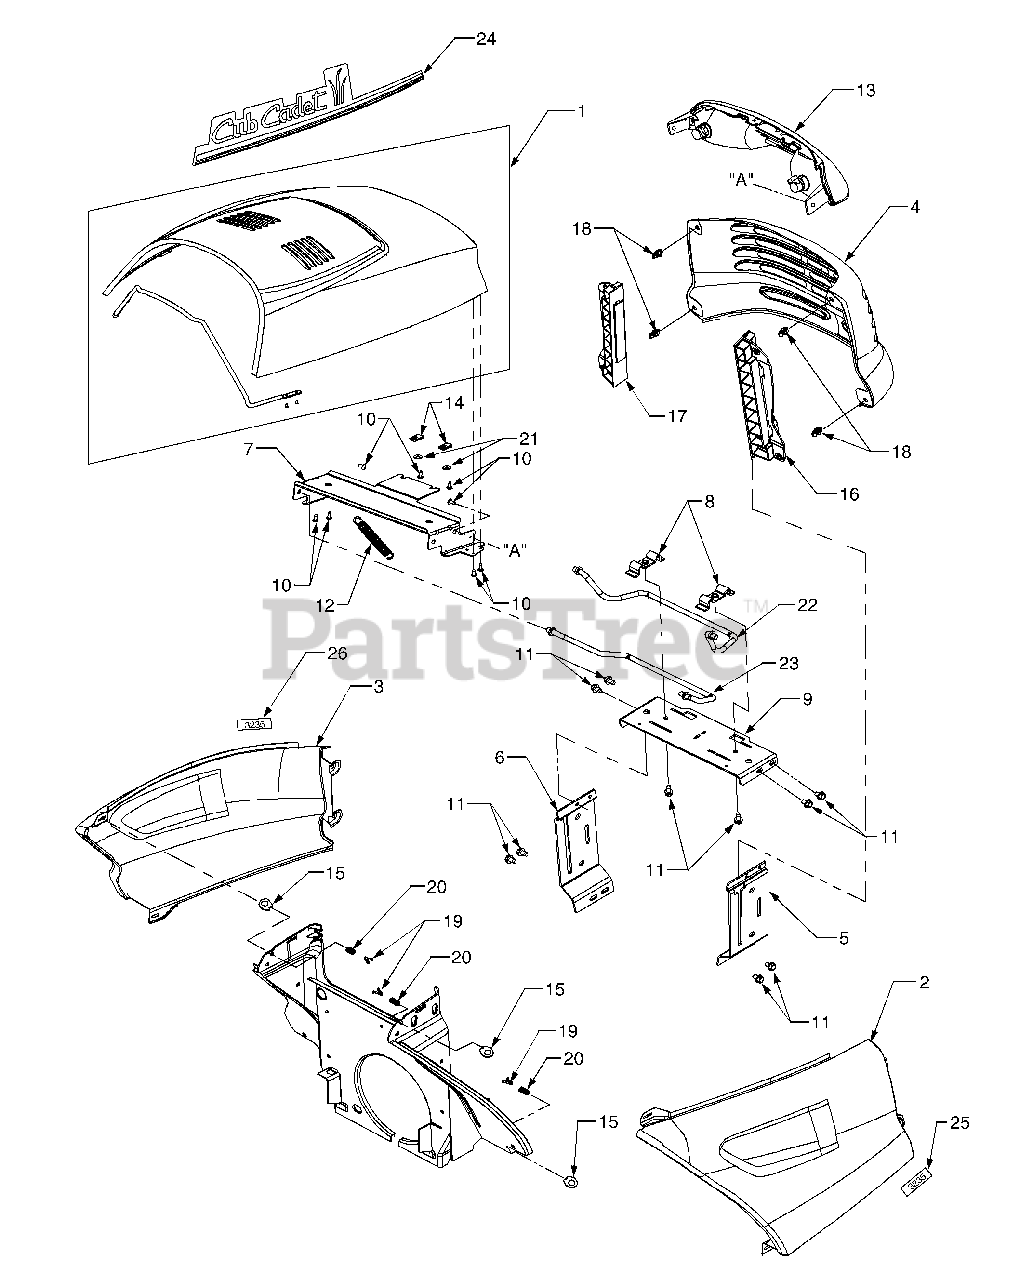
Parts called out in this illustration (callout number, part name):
1	Hood w/Support Rod Assembly
2	Side Panel, RH
3	Side Panel, LH
4	Grille, Series 3000
5	Support, Grille - RH
6	Support, Grille - LH
7	Bracket, Upper Hood
8	Bracket, Rod Retainer
9	Support, Hood
10	Screw, Truss Hd, Tapp, #10-16 x 5
11	Screw, Hex Wash. Hd. Tapp 5/16-18 x 5
12	Spring, Extension
13	Headlight Assembly
14	Nut, U-type Speed, #10
15	Latch, 1/4 Turn
16	Mount, Side Panel/Grille RH
17	Mount, Side Panel/Grille LH
18	Fastener, Grille Mount
19	Clip, Spring
20	Spring, Compression
21	Washer, Flat, .194 x .62 x .063
22	Rod, Upper Hood
23	Rod, Lower Hood
24	Graphic, Hood - RH
25	Graphic, 3235
